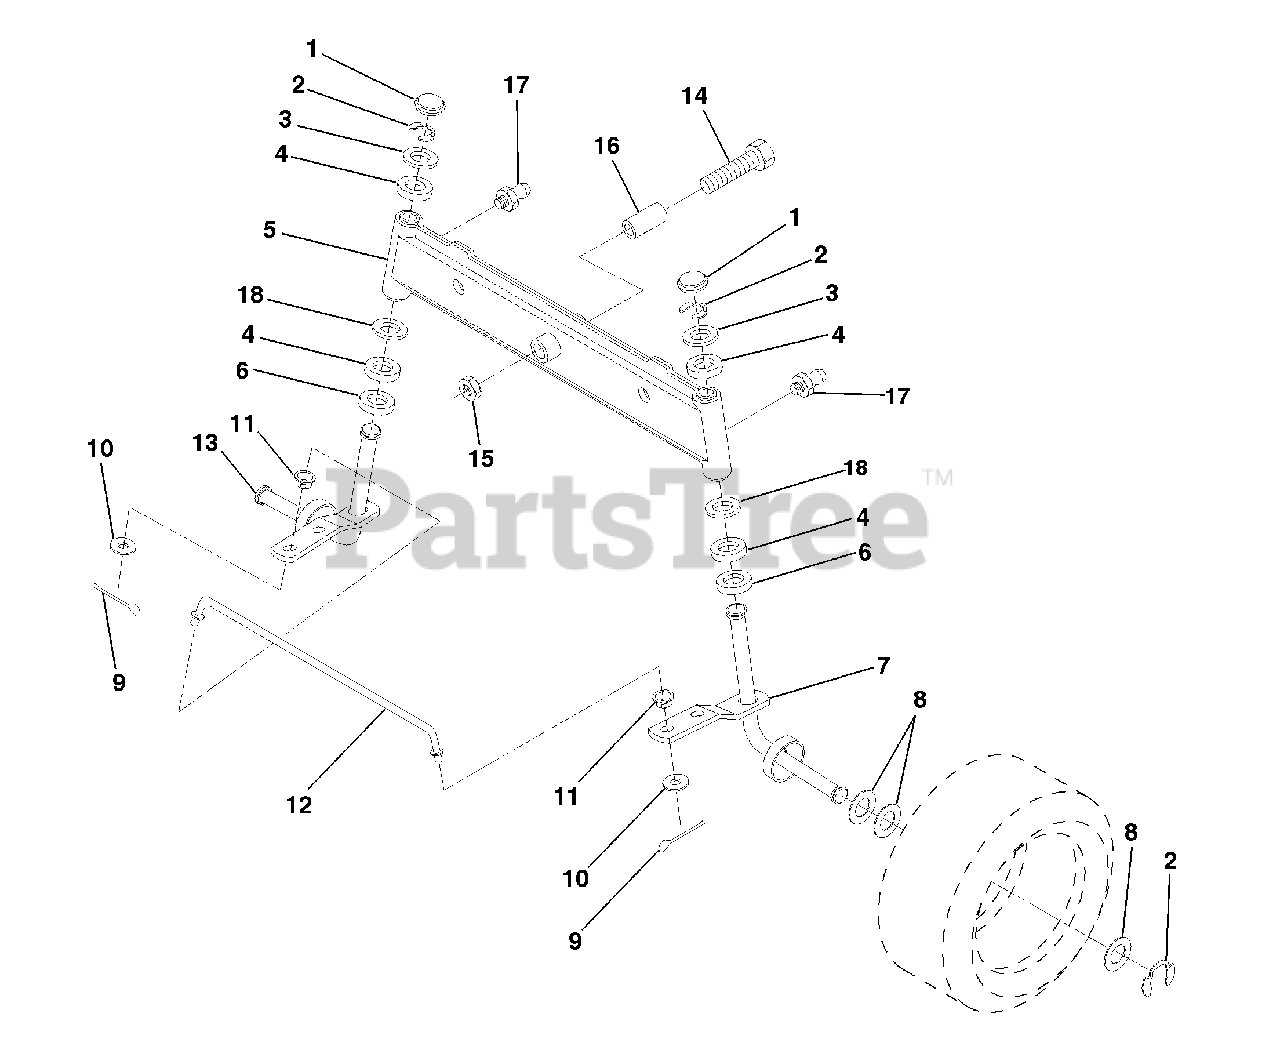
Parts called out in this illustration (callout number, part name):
1	Cap, Spindle
2	Ring, Clip
3	Washer 25/32 x 1-5/8 x 16 Gauge
4	Bearing
5	Axle, Front
6	Bearing, Thrust
7	Spindle Assembly, R.H.
8	Washer 25/32 x 1-1/4 x 16 Gauge
9	Pin, Cotter 1/8 x 3/4
10	Washer 13/32 x 13/16 x 16 Gauge
12	Tie Rod
13	Spindle Assembly, L.H.
14	Bolt Hex 5/8-11 Unc x 3-1/2
15	Nut Lock Flange 5/8-11 Unc
16	Spacer Bearing
17	Fitting Grease
18	Washer 27/32 x 1-1/4 x 16 Ga.
